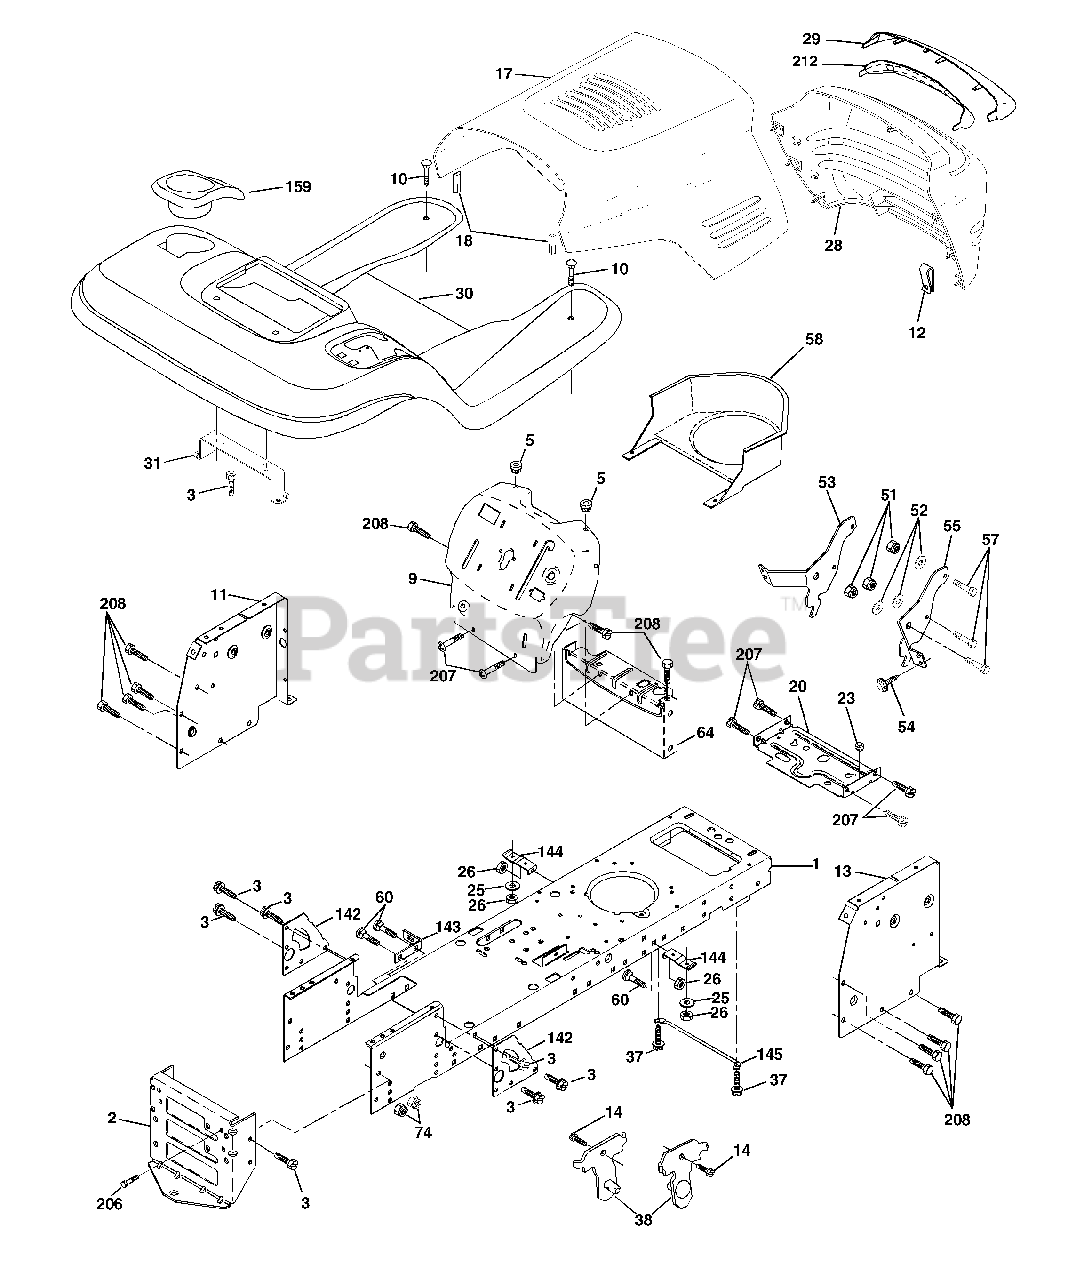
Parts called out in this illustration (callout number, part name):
1	Chassis Stamping
3	Screw 3/8-16x3/4
9	Dashboard
10	Bolt Rdhd Sqnk 3/8-16 Unc x 1
11	Panel Dash Lh
12	Clip Tinnerman Grille
13	Panel Dash Rh
14	Screw Thdrol 3/8-16 x 1/2
17	Hood
20	Plate Mtg Battery/Fuel Tank
25	Washer 13/32 x 13/16 x 12 Ga.
26	Nut Lock w/Insert 3/8-16 UNC
28	Grille Lens Asm
29	Lens
30	Fender
37	Screw Thdrol 5/16-18 x 1/2
38	Bracket Asm Pivot Mower Rear
51	Nut Lock w/Insert 1/4-20
52	Washer 9/32 x 7/8 x 16 Ga.
53	Bracket Grille Lh
54	Screw Hex Wshd 8-18 x 7/8
55	Bracket Grille Rh
57	Bolt Fin Hex 1/4-20 Unc x 3/4
60	Bolt RDHD SQNK 3/8-16 x 3/4
64	Dash Lower Stlt
74	Nut Crownlock 3/8-16
142	Plate Reinforcement
143	Bracket Swaybar Chassis
144	Bracket Ft Rest
145	Rod Pivot Chassis Hood
159	Cupholder YTGT Grey
206	Bolt Shoulder 5/16-18 TT
207	Screw Thdrol 5/16-18 x 1/2 TYTT
208	Screw Thdrol 3/8-16 x 1/2 Ty-TT
212	Insert Lens Reflect
